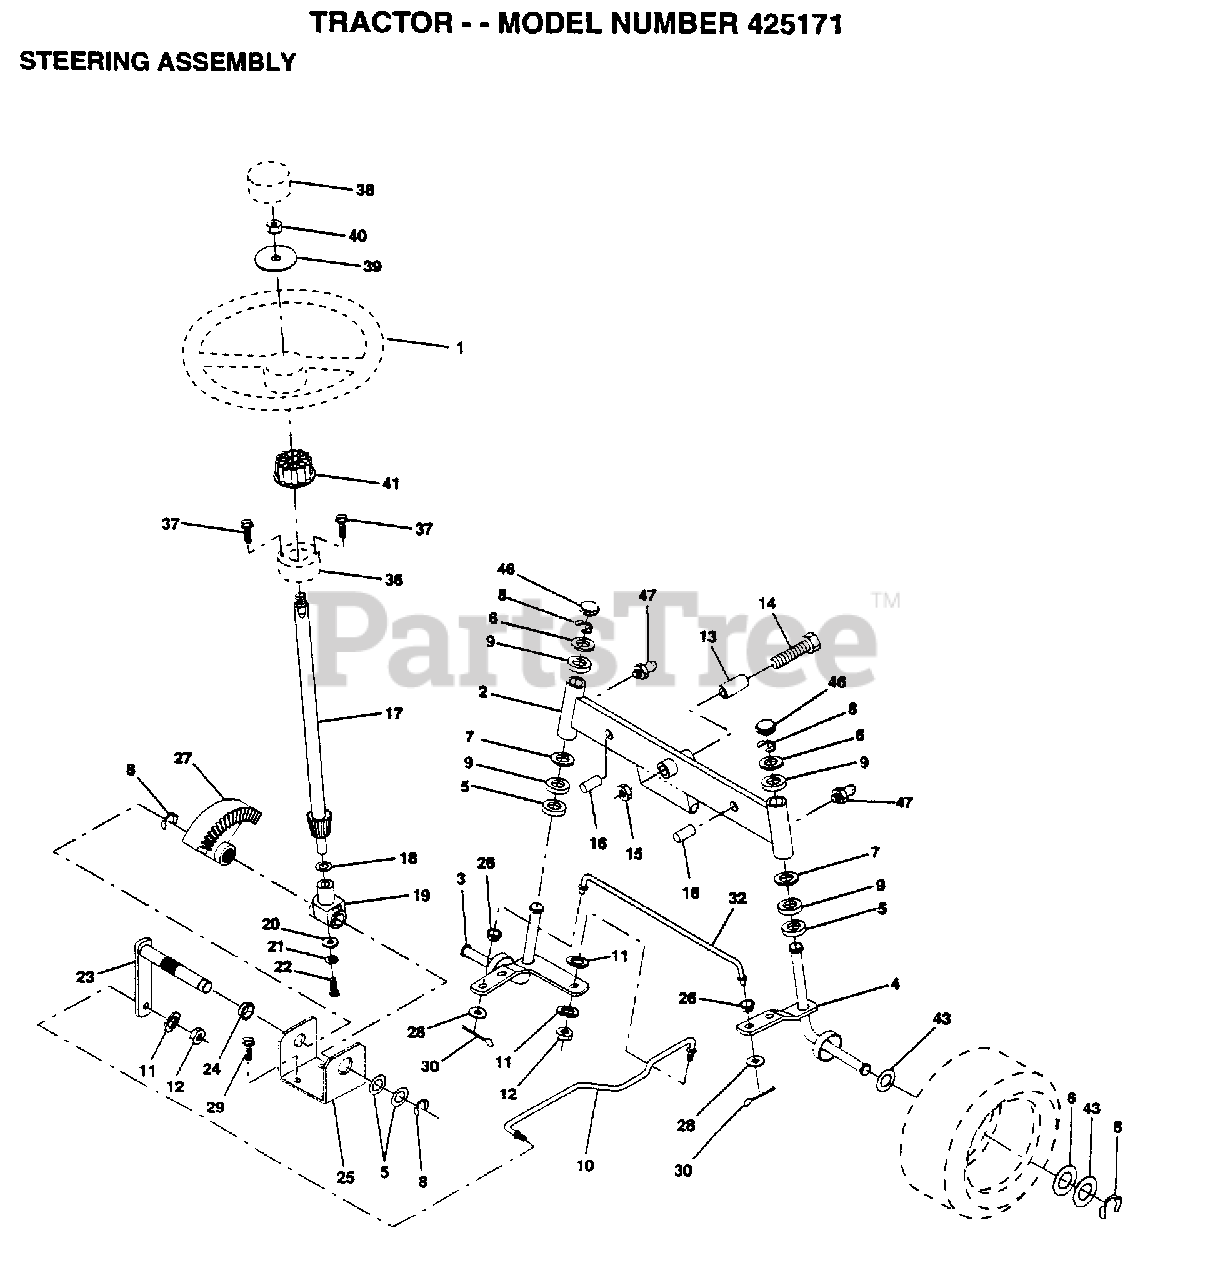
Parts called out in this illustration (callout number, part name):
2	AXLE ASM FRONT
3	SPINDLE LH
4	SPINDLE RH
5	WASHER .T
6	WASHER
7	WASHER
8	RING
9	COL. SRTG. BEAR.
11	LOCKWASHER
13	BEARING
14	BOLT HEX 5/8-11
15	"NUT-LOC,FLANGE LT"
16	AXLE PIN
17	STEERING SHAFT
18	THRUST WASHER
19	SUPPORT.SHAFT
21	LOCKWASHER
22	"SCREW,SPECIAL"
24	NYLINER T
25	"BRKT,STEERING"
26	BUSHING.DRAGLINK
27	GEAR SECTOR
28	WASHER
29	SCREW
30	COTTER PIN
32	TIE ROD
36	BUSHING.STRG.3/4
37	SCREW SLFTP #10-24X1/2
38	ST WHL INSERT CAP
39	WASHER
41	ADAPTER LT
43	WASHER
46	CAP
47	ZERK M
